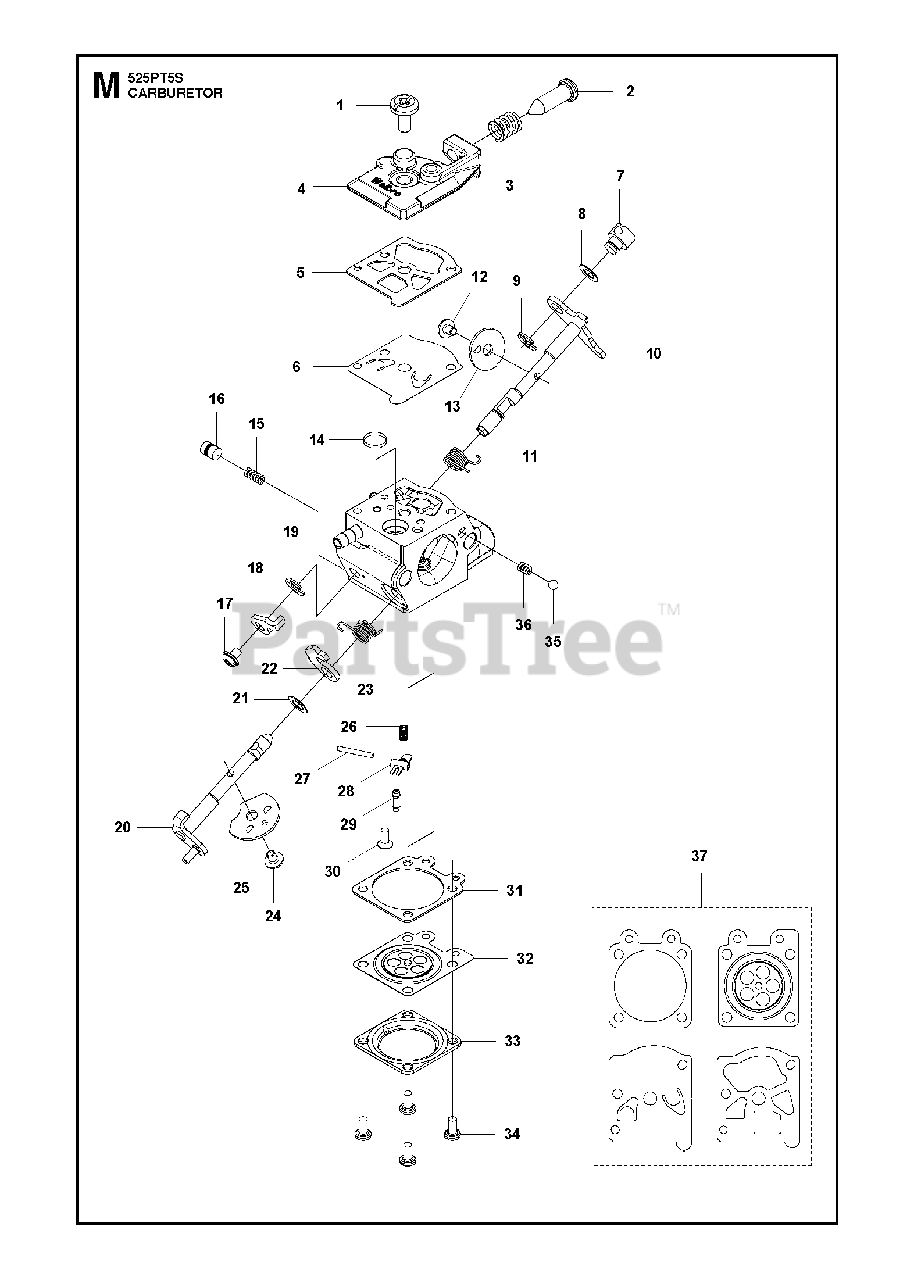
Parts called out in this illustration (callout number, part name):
2	SCREW, IDLE
4	COVER PUMP
6	DIAPHRAGM, FUEL PUMP
10	SHAFT ASSEMBLY,THROTTLE
14	SCREEN
16	PISTON ASSY
18	LEVER THROTTLE
20	SHAFT ASSEMBLY,CHOKE
29	VALVE INLET
34	SCREW ASSY
36	CHOKE SPRING
37	GASKET KIT
